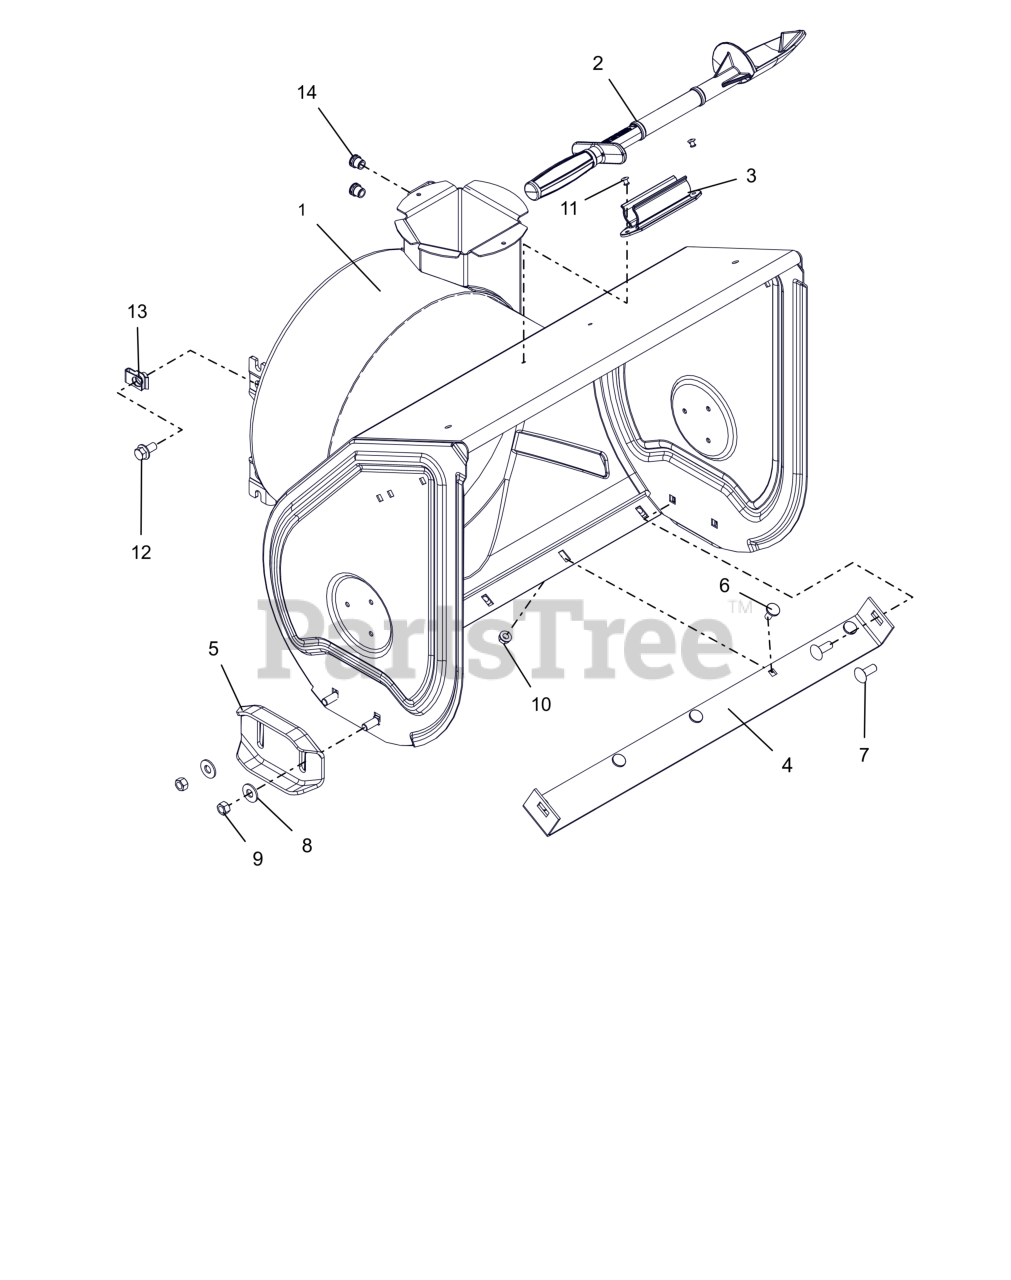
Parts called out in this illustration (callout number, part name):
1	BLOWER HOUSING W/DECAL 24"
2	DEVICE, SNOW CLEAN OUT
3	MOUNT, SNOW CLEAN OUT
4	BLADE, SCRAPER-24"
5	SKID SHOE, REVERSIBLE - ORANGE
6	BOLT, MODIFIED HEAD CARRIAGE
7	BLT,RHSSN .38-16X1.00 G5 ZCC
8	WSHR,FLT .438X1.00X.083 ZCC
9	NUT-LK-CTR .38-16 ZC120
10	NUT-LK-TOP-FLG .312-18 GF ZCC
11	RVT, POP .1875 ZCC
13	NUT-RTNR .375-16X.37
14	NUT,THD,INSERT .38-16 ZC120
